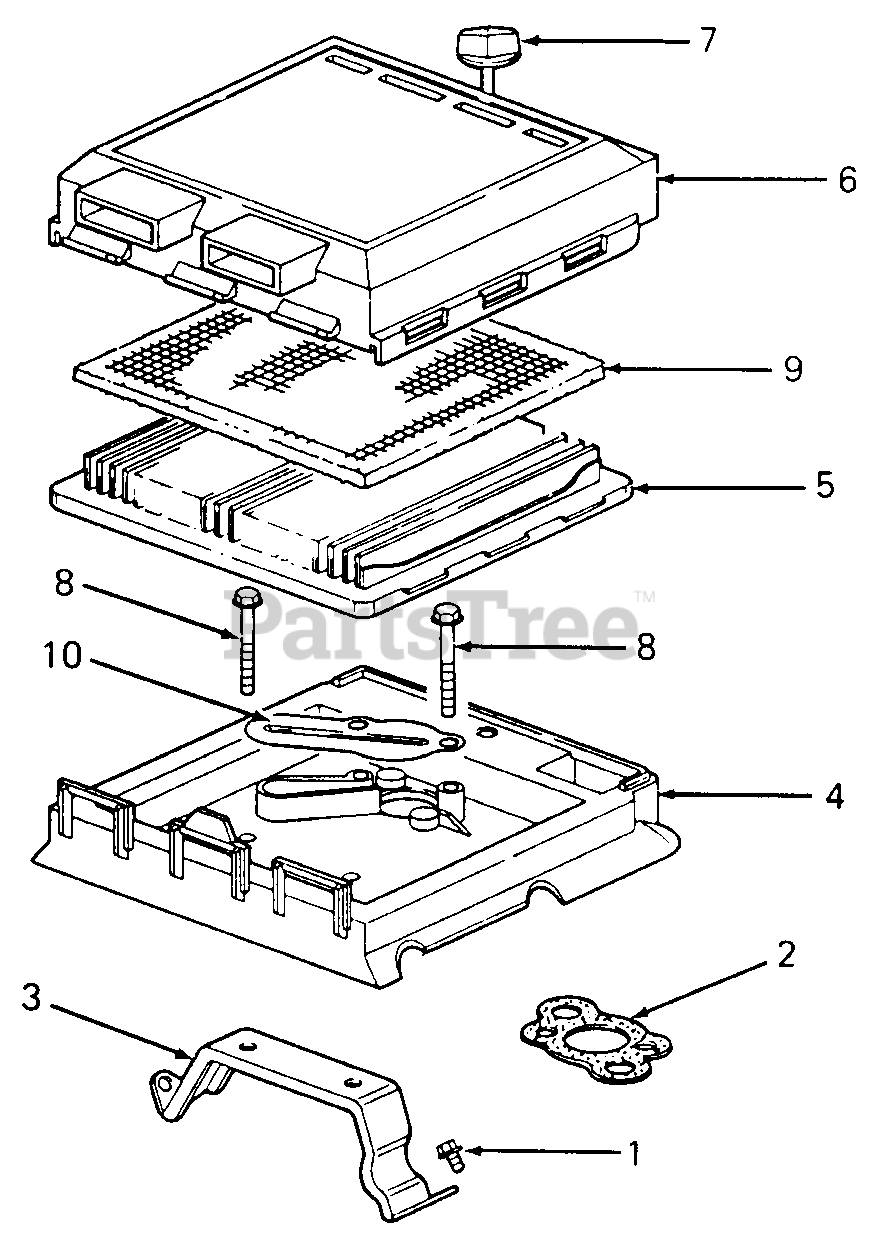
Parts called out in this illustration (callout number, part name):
1	Screw, Sems
2	Gasket, Air Cleaner
3	Bracket, Air Cleaner
4	Base, Air Cleaner
5	Filter, Air Cleaner
6	Cover, Air Cleaner
7	Screw, Air Cleaner Mtg
9	Pre-Filter
